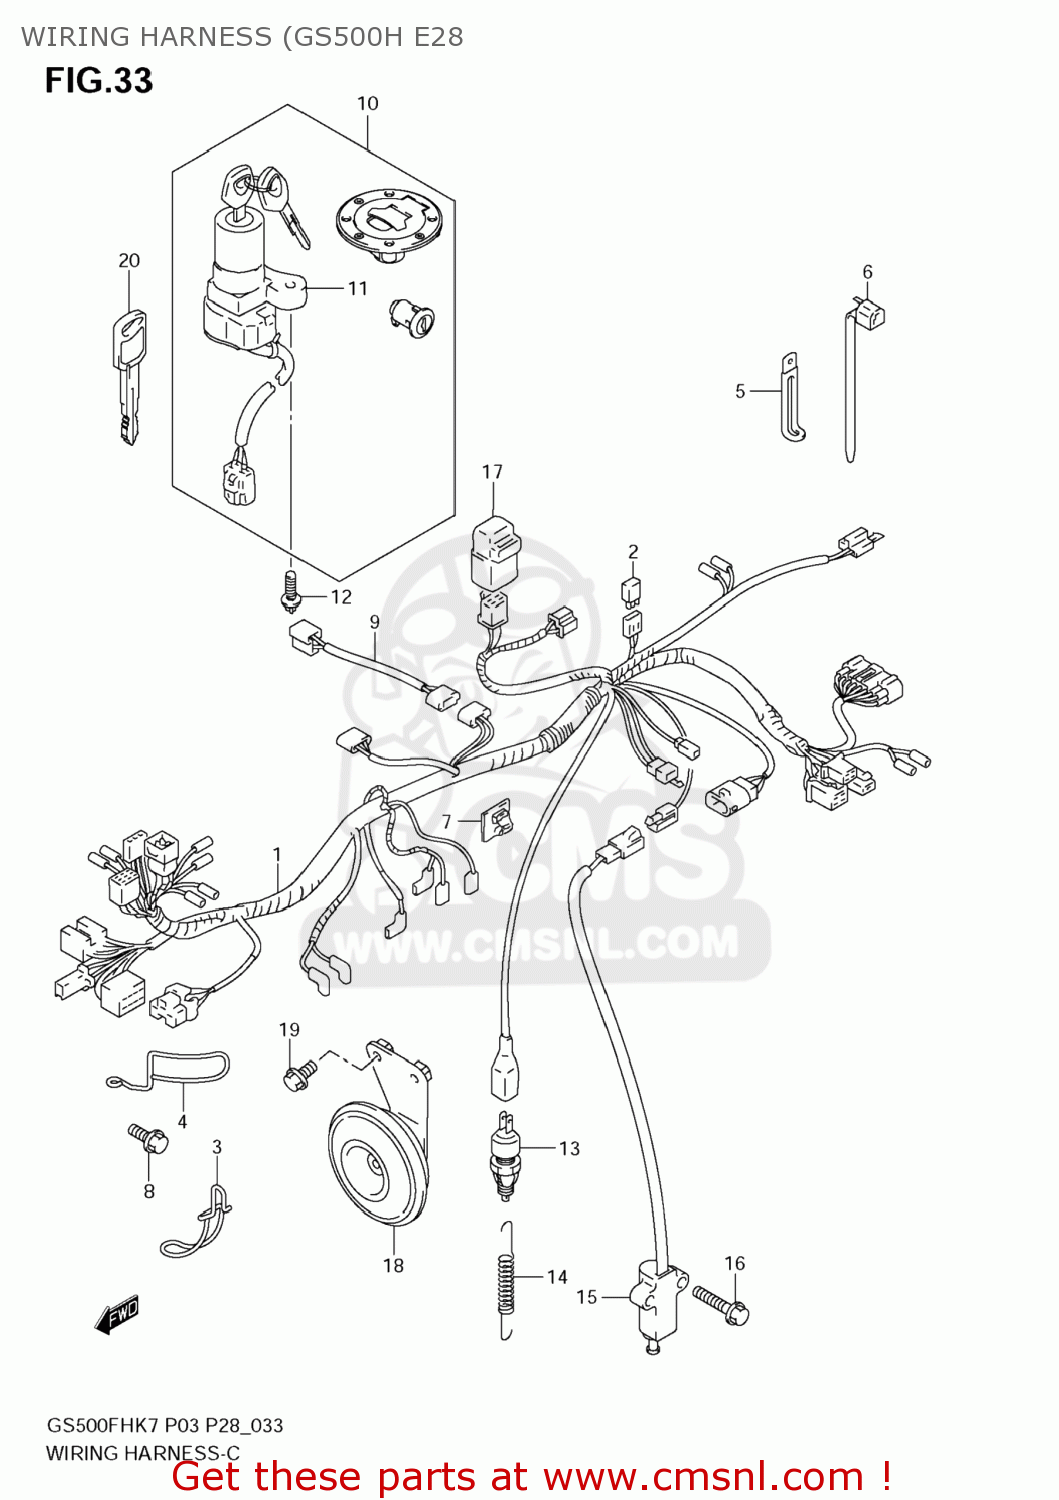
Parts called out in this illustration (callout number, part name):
1	HARNESS, WIRING
2	DIODE
3	PROTECTOR
4	PROTECTOR
5	CLAMP(L:45)
6	CLAMP
7	CLAMP
8	BOLT UH125&200
9	WIRE,AIR SOLENOID
10	LOCK SET
11	LOCK ASSY,STEERING
12	SCREW(6X18)
13	SWITCH ASSY,STOP LAMP
14	SPRING
15	SWITCH ASSY,SI
16	BOLT
17	RELAY ASSEMBLY
18	HORN ASSY
19	BOLT
20	KEY,BLANK
